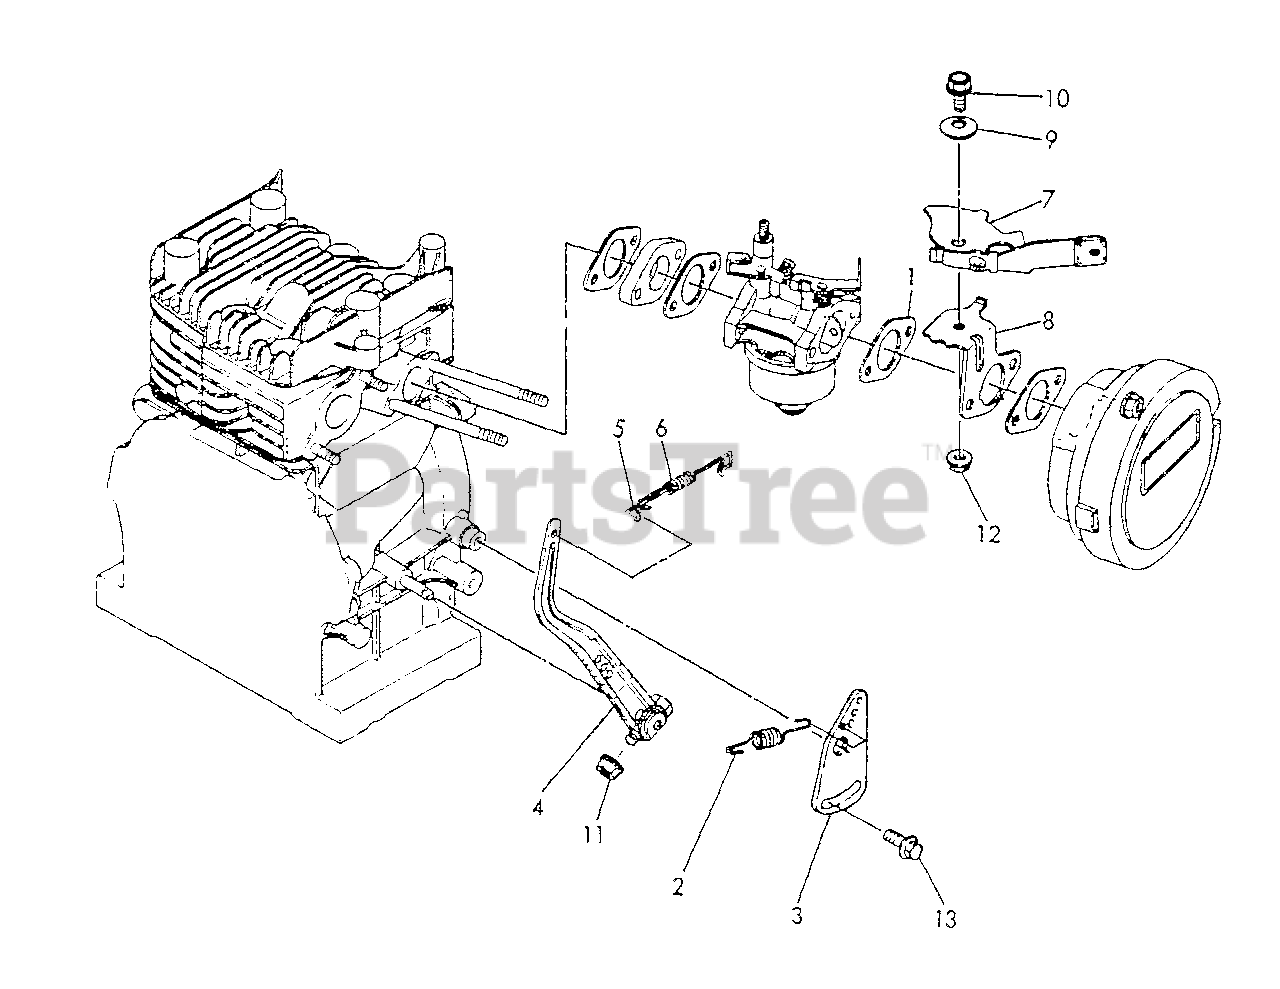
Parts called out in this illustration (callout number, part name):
1	GASKET, INTAKE
2	SPRING, REGULATOR
3	HANDLE, REGULATOR
4	LEVER, GOVERNOR
5	LINK, THROTTLE
6	SPRING, TENSION
7	LEVEL ASSY
8	BRACKET
9	COLLAR
10	BOLT - 6×12 -- PLATED
11	U-NUT M6
12	U-NUT M8
13	BOLT - 6×8 -- PLATED
